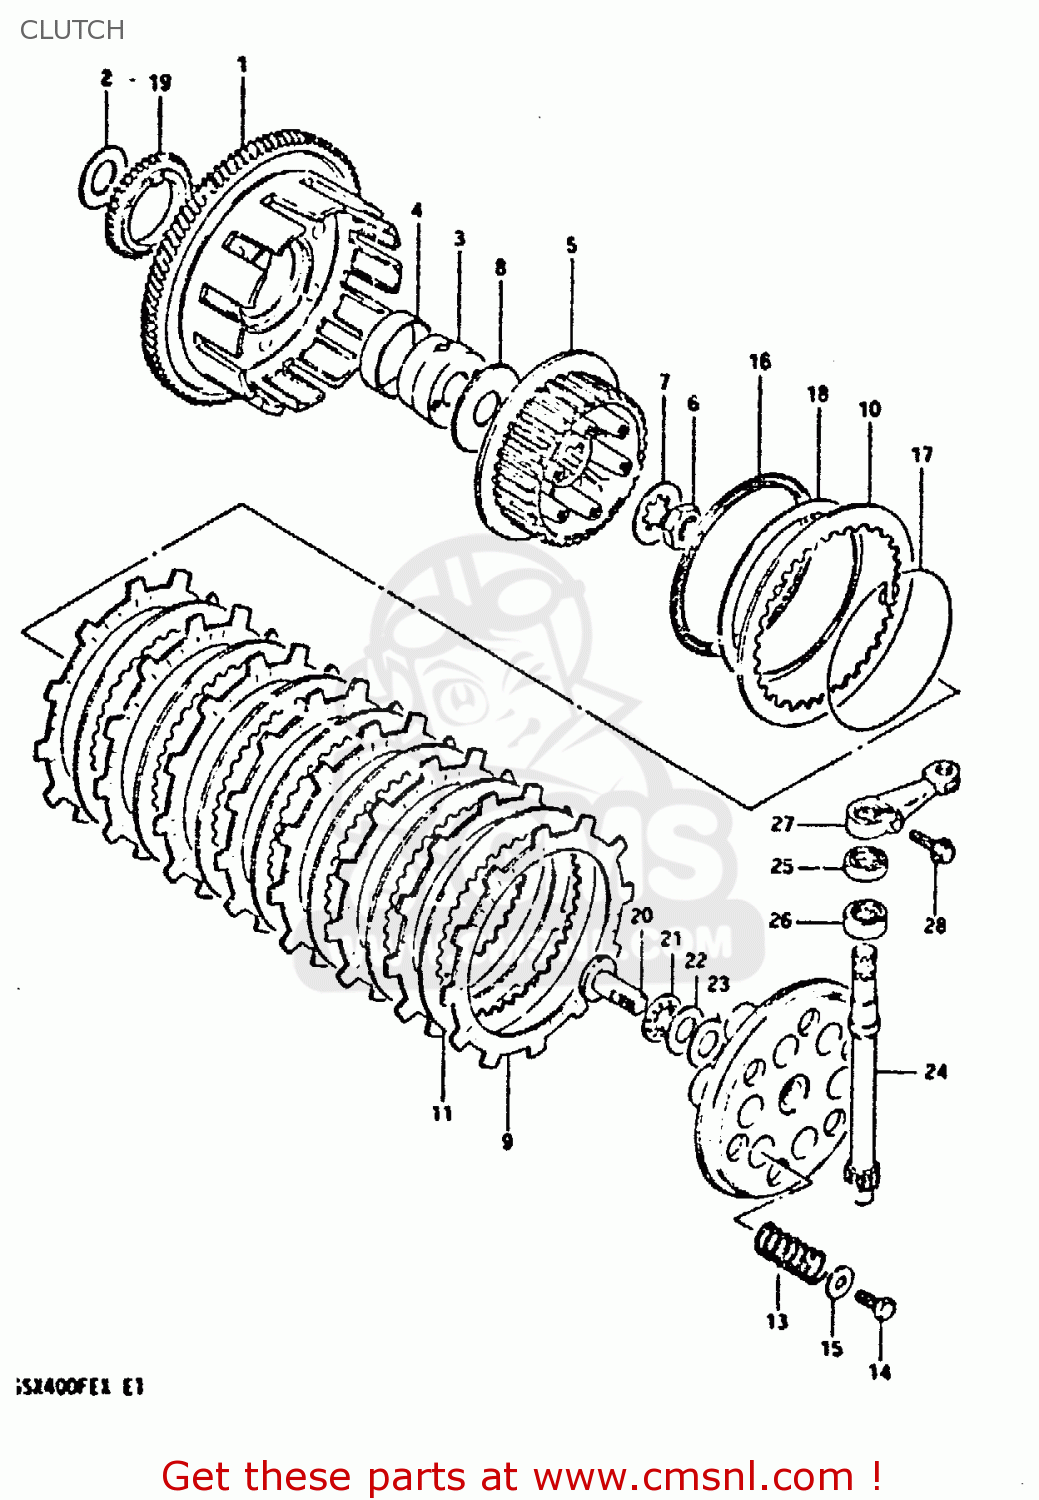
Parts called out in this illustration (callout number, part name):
1	GEAR, PRIMARY DRIVEN (NT:92)
2	WASHER (22X40X1.5)
3	SPACER
4	WASHER
5	HUB, SLEEVE
6	NUT
7	WASHER,LOCK
8	WASHER
9	PLATE,CLUTCH DRIVE (MCA)
10	PLATE,CLUTCH DRIVEN(T:2.0) (NAS)
11	PLATE,CLUTCH DRIVEN (NAS)
12	DISC,CLUTCH PRESSURE
13	SPRING
14	BOLT, UPPER
15	WASHER
16	SEAT,WAVE WASHER
17	RING,STOPPER
18	WASHER
19	GEAR, OIL PUMP DRIVE (NT:38)
20	RACK,CLUTCH RELEASE
21	BEARING(15X28X2)
22	WASHER
23	PINION, RELEASE
24	OIL SEAL
25	BEARING(15X22X12)
26	ARM,CLUTCH RELEASE
27	BOLT,REAR
